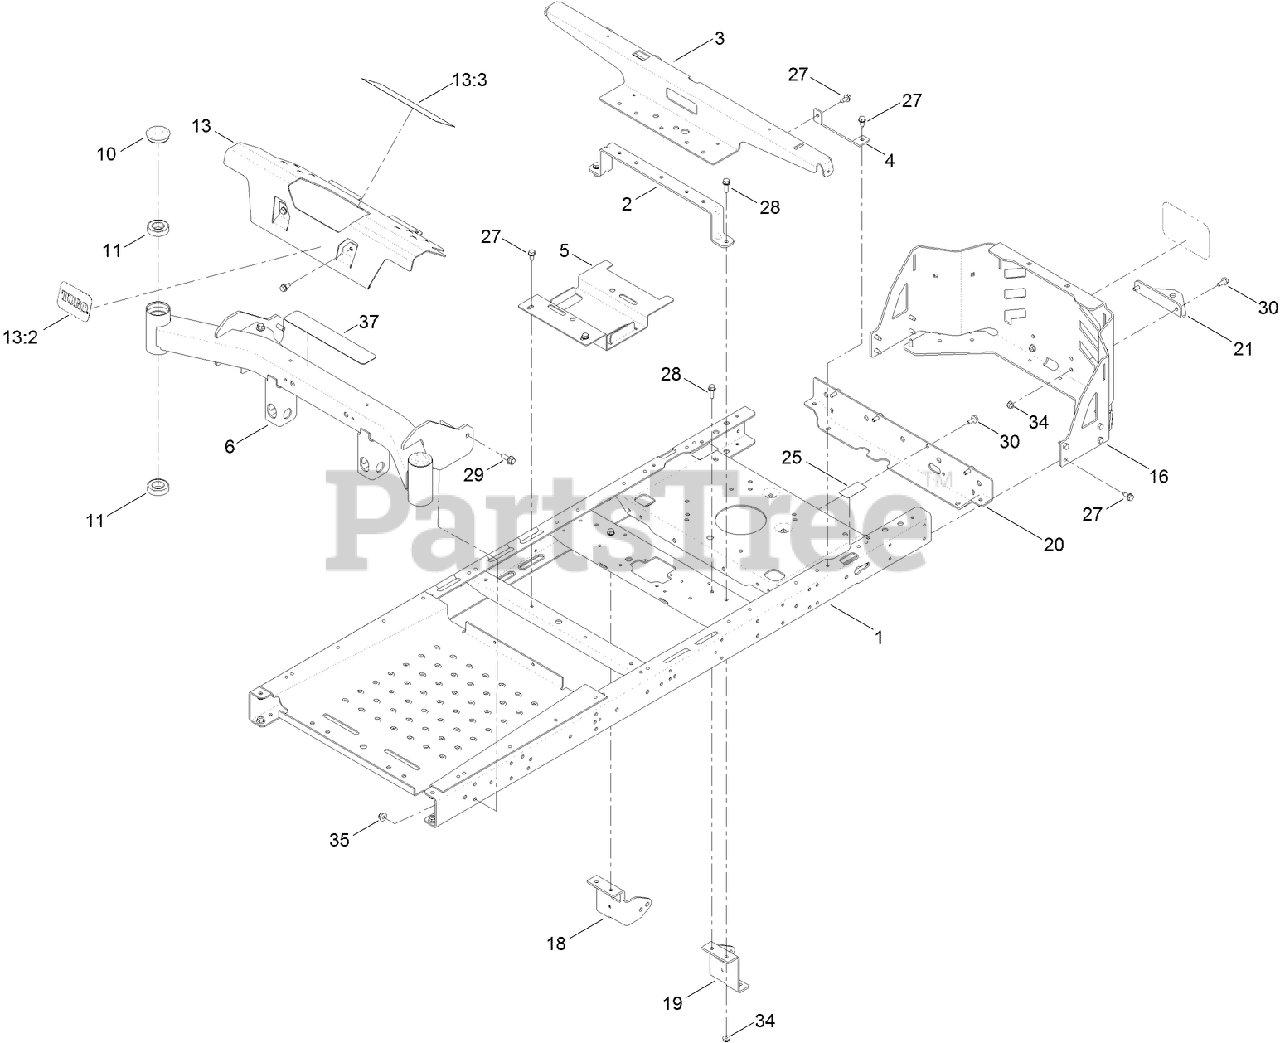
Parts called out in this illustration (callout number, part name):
1	FRAME ASM
2	BRACE-SEAT, REAR
3	SUPPORT-POD
4	SUPPORT-TANK, REAR
5	BRACKET-BATTERY
6	FRONT AXLE ASM
10	CAP-GREASE
11	BEARING-BALL
13	FOOTREST
13:3	DECAL-DANGER
16	GUARD-ENGINE
18	MOUNT-HYDRO, FRONT (RH)
19	MOUNT-HYDRO, FRONT (LH)
20	CROSSMEMBER-REAR, WIDE
21	BRACKET-HITCH
25	DECAL-BYPASS
27	SCREW-HWHTF
28	SCREW-HHF
29	SCREW-HHF
30	SCREW-HHF
34	NUT-HF, NI
35	NUT-HF, NI
37	TREAD-STEP
